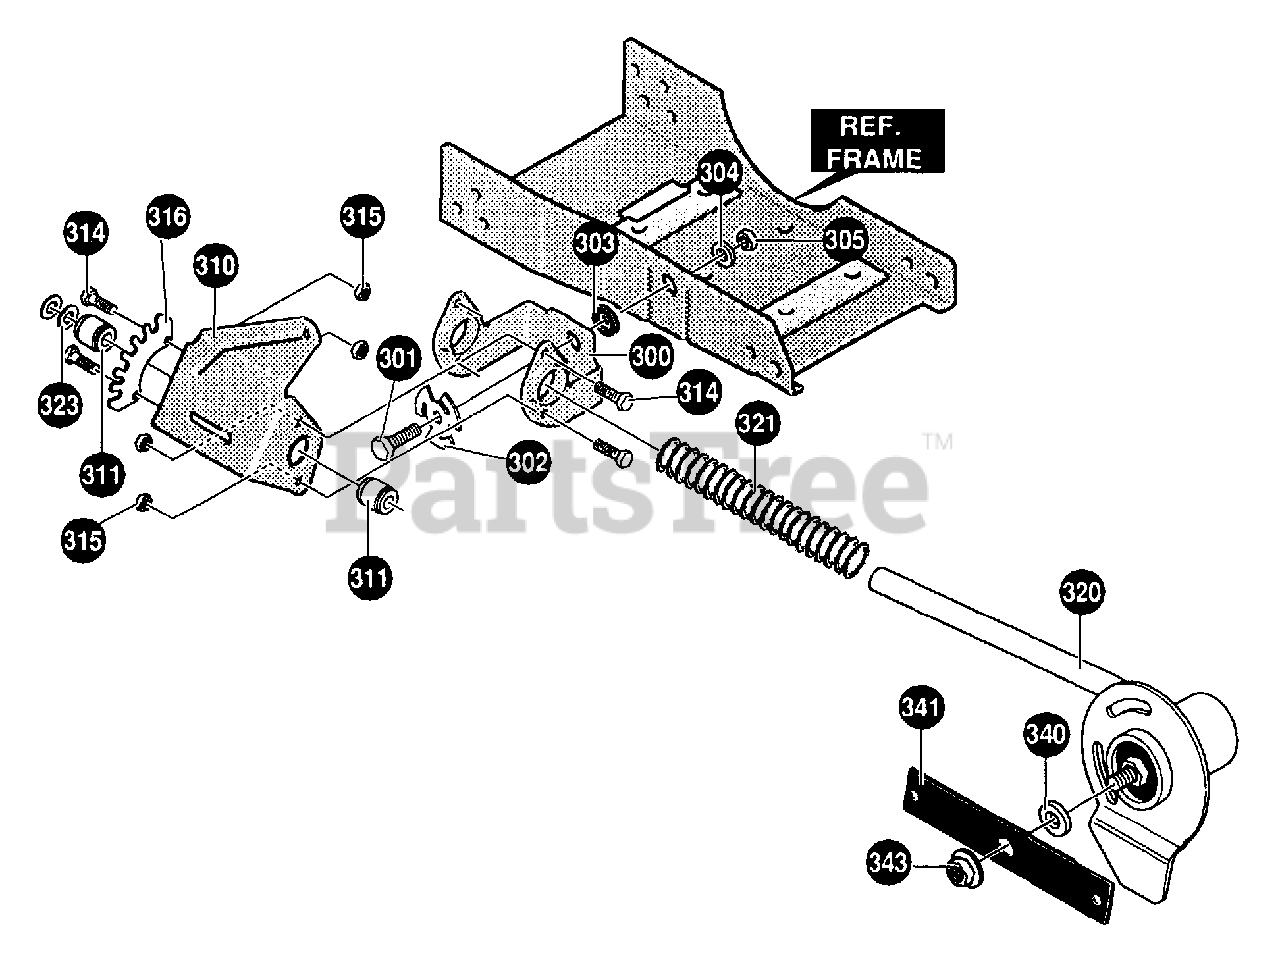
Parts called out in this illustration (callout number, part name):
300	SUPPORT ARM-INNER
301	BOLT, 3/8-16 SHOULDER
302	WASHER, SPRING
303	SPACER, QUICK WHL
304	FLATWASHER, .390X1.25X.119
305	NUT, 3/8-16 REGHXCTRL
310	SUPPORT ARM-OUTER
311	BRNG, SFAL. IDX. ODX.
314	SCREW, 1/4-20X.75 HHC
315	NUT, 1/4-20 REGHEXCTRLK
316	PLATE, INDEX
320	QUILL, ASSY
321	SPRING
323	FLATWASHER, .640X1.25X.06
340	FLATWASHER .515X1.38X.119PL
341	BLADE, EDGER 2PT
343	NUT, 1/2-20 WDFL
